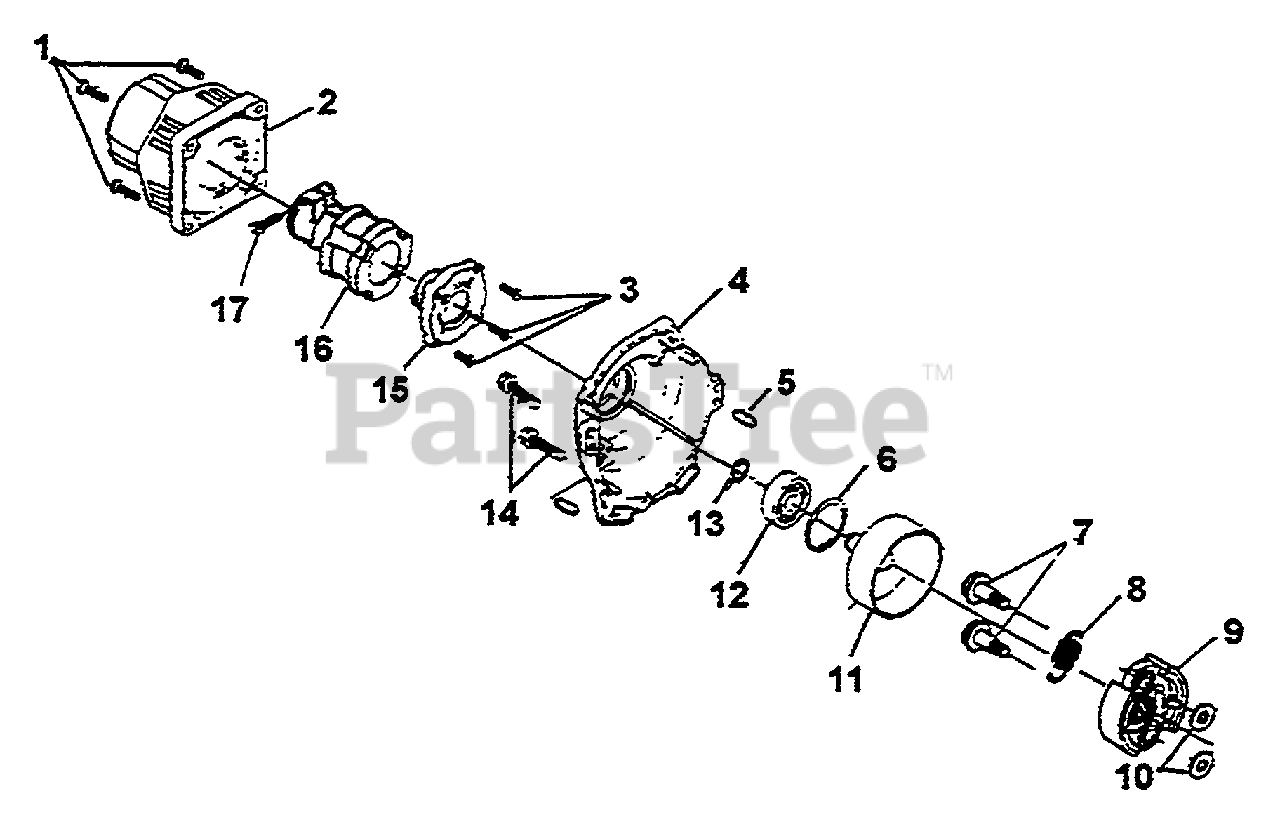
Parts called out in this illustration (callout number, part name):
1	BOLT & WASHER
2	CLUTCH CASE
4	CASE-COVER
5	PIN, DOWL
6	SNAP RING
7	BOLT, CLUTCH
8	SPRING, CLUTCH
9	CLUTCH KIT
10	WASHER
11	CLUTCH DRUM
13	SNAP RING
14	BOLT & WASHER
15	BEARING COVER
16	INSERT RING
